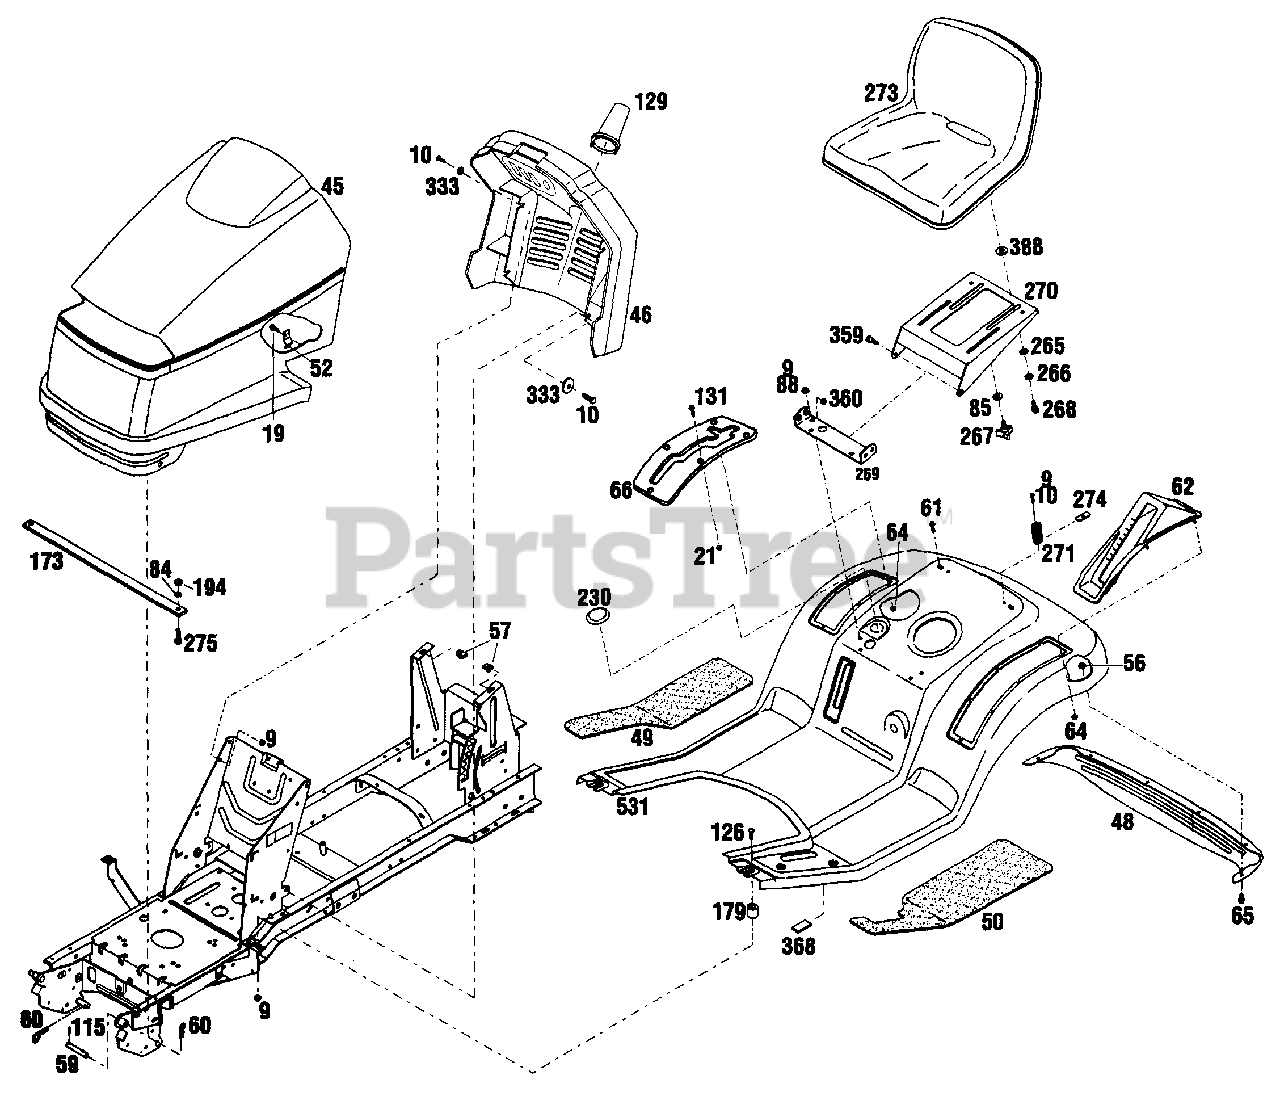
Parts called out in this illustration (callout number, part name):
9	Flange Nut, 5/16-18
10	Hex Head Capscrew, 5/16-18 x 3/4
19	Self Threading Screw, #10
21	Nylon Locknut 1/4-20
48	Rear Fender Trim
49	Right Foot Pad
50	Left Foot Pad
56	Flange Nut, 1/4-20
57	Self-Retaining Nut, 5/16-18
59	Hood Pivot Pin
60	Cotter Spring, 1/8
61	Screw, 5/16-18 x 7/8
62	Lift Handle Cover
64	Self-Threading Nut, 1/4
65	Flange Screw, 1/4-20 x 1/2
84	Lock Washer, 1/4
85	Flat Washer, 3/8
88	Carriage Bolt, 5/16-18 x 5/8
115	Drive Pin, 3/16 x 1
126	Carriage Bolt, 5/16-18 x 3/4
129	Steering Cover
131	Screw, 1/4-20 x 5/8
194	Nut, 1/4-20
265	Nylon Washer, 3/8
266	Bowed Washer, 3/8
267	Adjusting Knob
268	Shoulder Bolt, 3/8-16
269	Seat Bracket
270	Seat Support
271	Compression Spring
274	Spring Hold-Down Bracket
275	Screw, 1/4-20 x 5/8
333	Flat Washer 5/16 x 1-1/2
359	Hex Head Cap screw, 3/8-16 x 7/8
360	Locknut, 3/8-16
388	Flat Washer
531	Rear Fender
